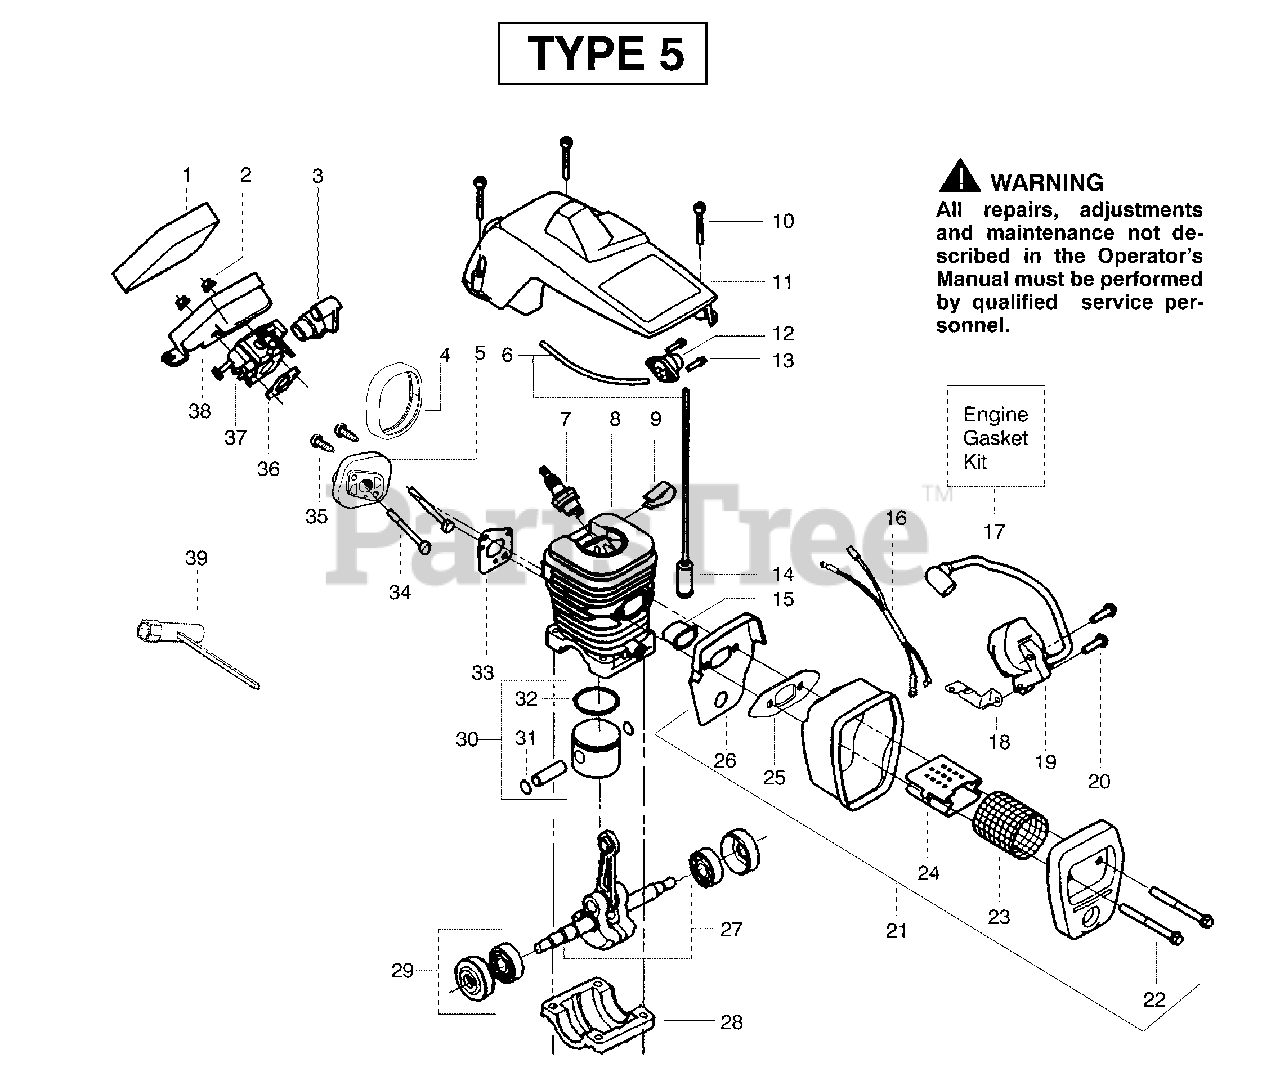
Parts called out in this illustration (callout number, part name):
1	Foam - Air Filter
3	Grommet-Carb Adjust
4	Seal-Carb Adapter
5	Carb. Adapter
6	Fuel Line Kit (Small)
7	Spark Plug (RCJ-7Y)
8	Kit-Cylinder
9	Clip-High Tension Lead
11	Cylinder Shield
12	Air Purge Ass'y.
14	Fuel Pick-up Ass'y.
15	Heat Insulator
16	Assy. -Wire Harness
17	Kit-Engine Gasket
18	Strap-Ground
19	Module- Ignition
21	Assy-Muffler
23	Screen-Spark
24	Diffuser-Muffler
25	Gasket-Muffler (kit)
26	Backplate-Muffler
27	Assy. - Crankshaft
28	Cap-Crankcase
29	Assy.-Seal & Bearing
30	Kit-Piston
31	Retainer-Piston Pin
32	Ring - Piston
33	Gasket-Carb. Adap. (kit)
36	Gasket - Carb. (kit)
37	Kit-Carburetor (Walbro WT-624)
38	Housing- Air Filter
39	Wrench - Bar
